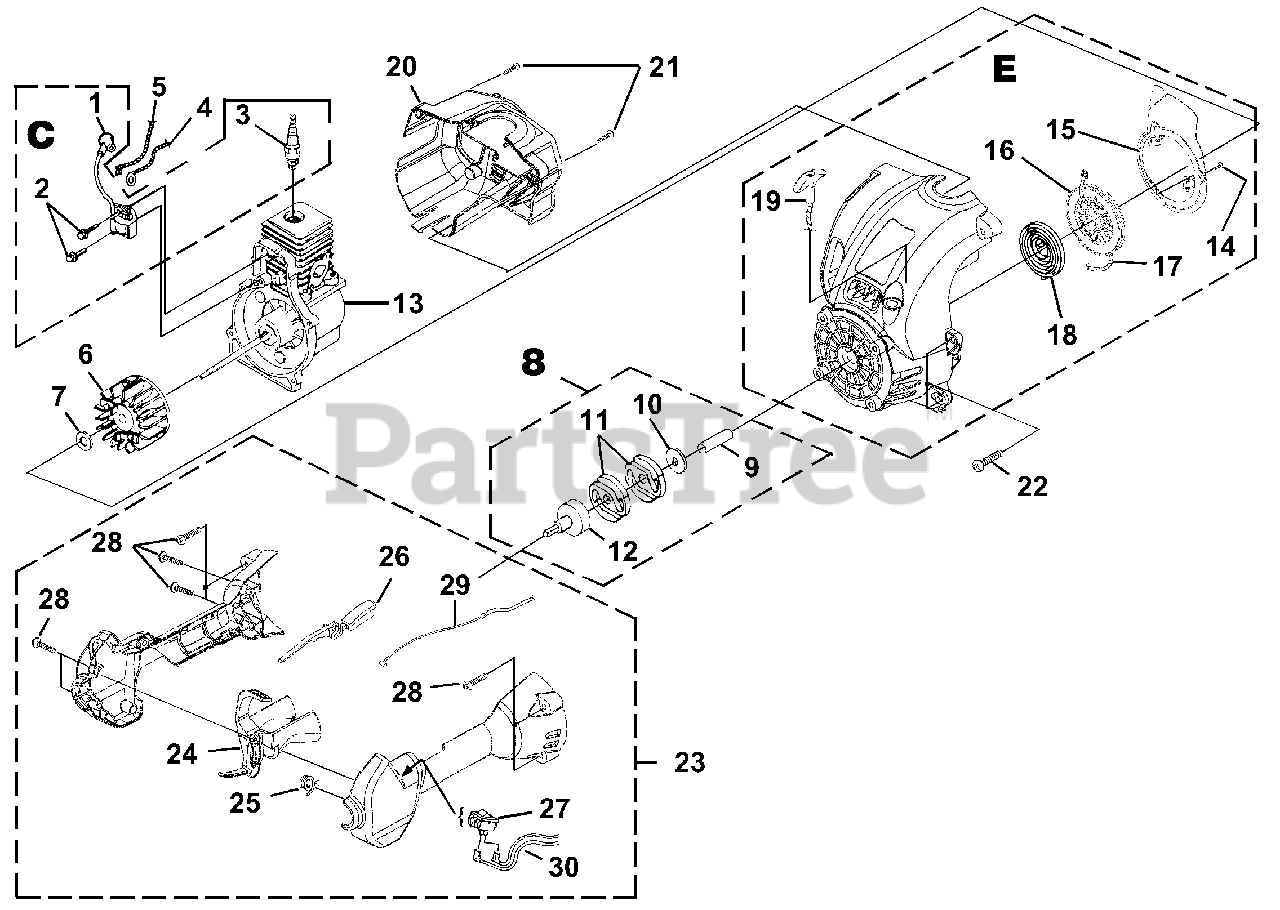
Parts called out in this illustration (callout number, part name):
1	TERMINAL & COVER
2	SCREW-Taptite (8-32 X 1")
3	SPARK PLUG
4	LEAD-Electrical
5	LEAD-Electrical
6	ROTOR KIT
7	WASHER-Flat
8	CLUTCH AND DRUM KIT
9	SPACER
10	WASHER-Flat
11	CLUTCH
12	CONNECTOR AND DRUM
13	SHORT BLOCK
14	SCREW-Thread Form (8-16 X 1/2")
15	BAFFLE-Air
16	PULLEY-Starter
17	ROPE-Starter (42")
18	SPRING & CONTAINER
19	GRIP-Starter (Yellow)
20	HOUSING-Rear Kit
21	SCREW-Plastite (10-14 X 7/8")
22	SCREW-Taptite (10-24 X 3/4")
23	CONTROL HANDLE ASSY.
24	TRIGGER-Throttle
25	SPRING
26	THROTTLE INTERLOCK
27	SWITCH
28	SCREW-Taptite (10-14 X 1")
29	CABLE-Throttle
30	LEAD-Electrical
C	IGNITION KIT
E	COMPLETE STARTER ASSEMBLY
